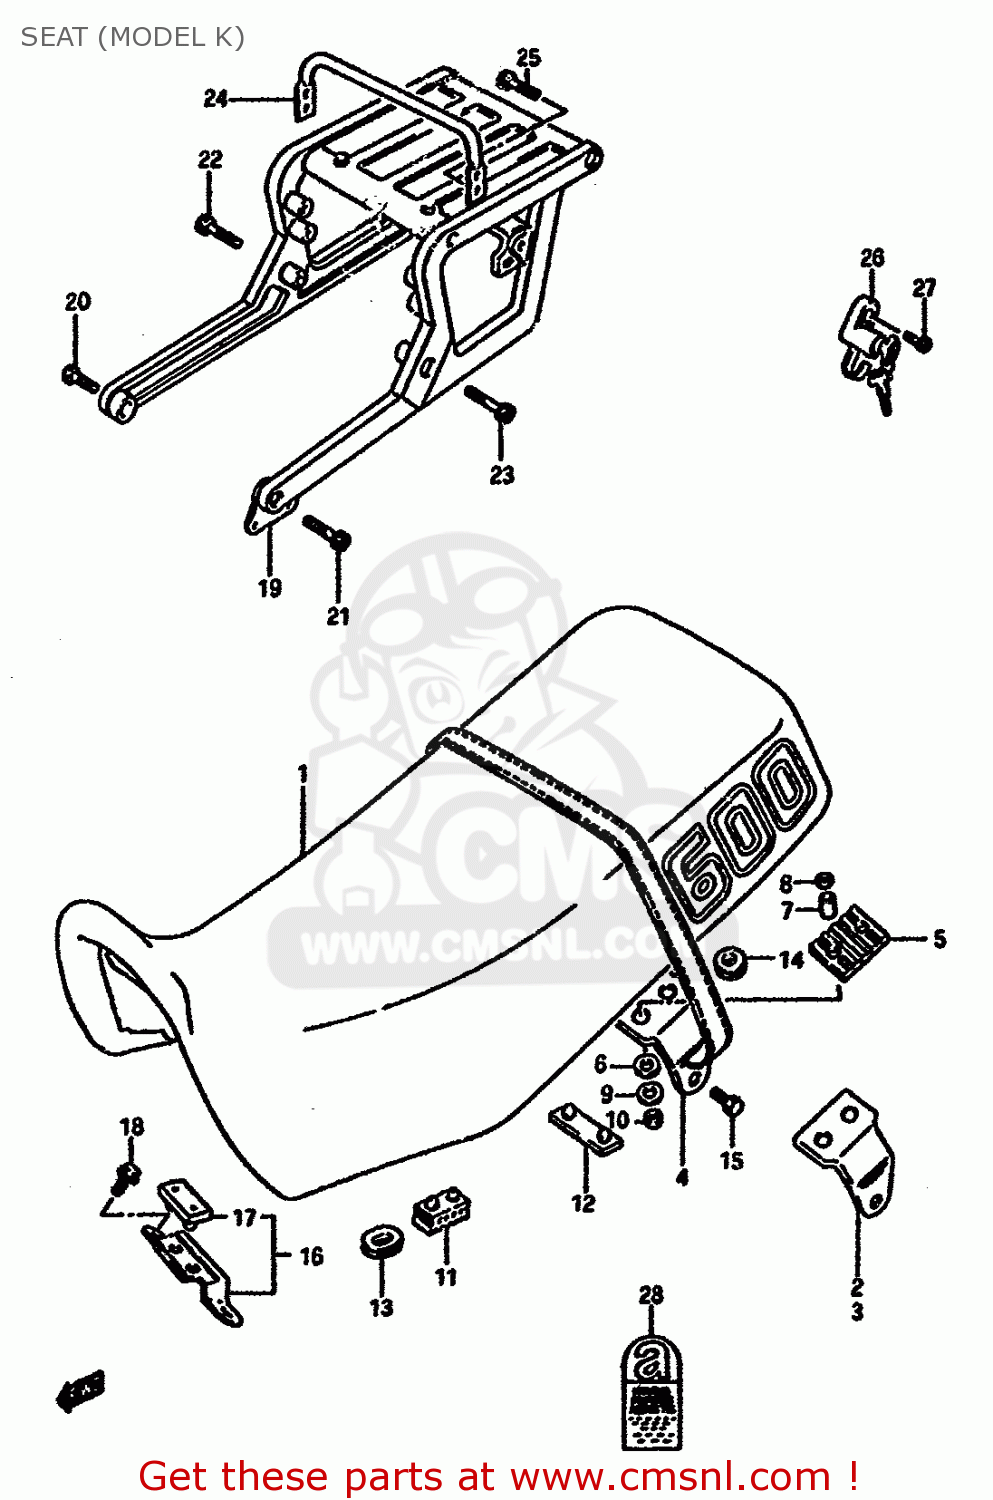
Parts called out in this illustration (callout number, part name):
1	SEAT SET (BLUE)
2	BRACKET,SEAT,RIGHT
3	BRACKET,SEAT,LEFT
4	BAND,SEAT
5	CUSHION,SEAT FR
6	CUSHION,FR PLATE
7	SPACER,SEAT SUPPORT
8	WASHER
9	WASHER, LOWER
10	NUT
11	CUSHION,SEAT(40X20X15)
12	CUSHION
13	CUSHION
14	CUSHION
15	BOLT, 8X1.25X1
16	PLATE ASSY,SEAT FR HOOK
17	CUSHION
18	BOLT
19	CARRIER ASSEMBLY,REAR
20	BOLT, FRONT RH
21	BOLT
22	LOCK WASHER
23	WASHER
24	BOLT (8X70)
25	BOLT 8X16
26	BOLT, FRONT RH
27	BOLT
28	BOLT, REAR RH
29	BOLT ,8X50
30	TUBE, PILLION HANDLE
31	BOLT 8X16
32	LOCK SET,HELMET
33	BOLT
34	LABEL,ASBESTOS WARNING
